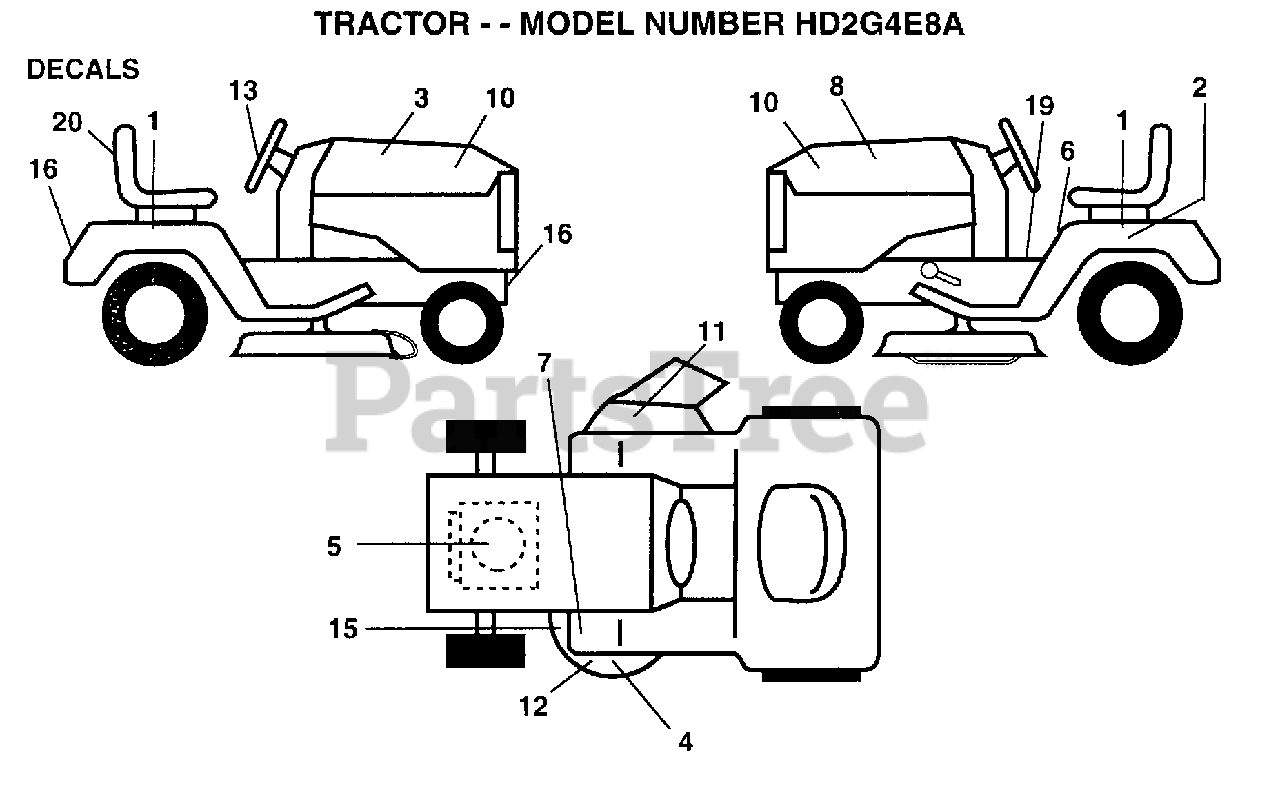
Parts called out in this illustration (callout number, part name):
1	DECAL.FEND.QUICKS
2	DECAL.BTRY.DANGER
3	DECAL.HD.RH.12.5
4	DECAL.DECK.MULCH.
5	DECAL, ENGINE
6	DECAL CAUT FEND
7	DECAL CLUT/BRAKE
8	DECAL.HD.LH.12.5
10	DECAL.PNL.SD.HDPO
11	"DECAL, WARNING"
12	DECAL.SCH.PRIM.42
13	DECAL.INST.WHL.ST
15	DECAL.SCH.DRV.42
16	DECAL.FENDER.HDEP
19	DECAL.SADDLE.INST
20	DECAL.SEAT.HDPT.
